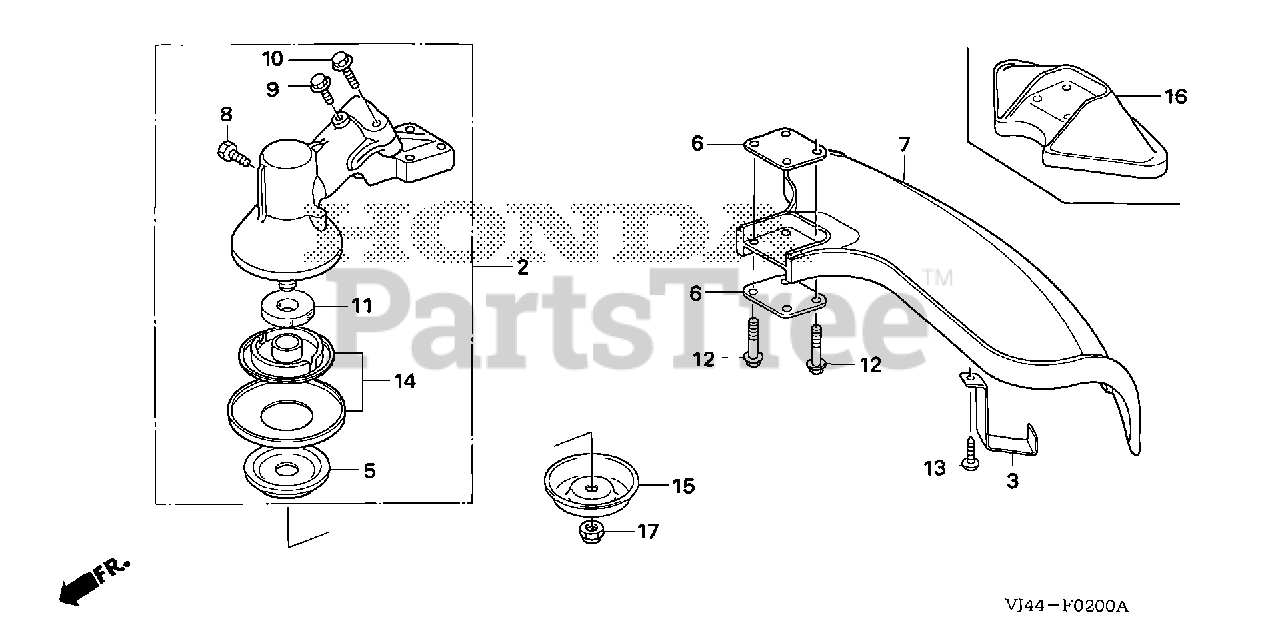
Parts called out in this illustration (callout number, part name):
2	CASE ASSY., GEAR
3	PLATE, NYLON CUTTING
5	HOLDER B, BLADE
6	SPACER, DEFLECTOR
7	DEFLECTOR, GRASS
8	BOLT, HEX. (8X10)
9	BOLT-WASHER (5X12)
10	BOLT-WASHER (5X25)
12	BOLT-WASHER (5X28)
13	SCREW, TAPPING (5X12) (PO)
14	HOLDER, BLADE
